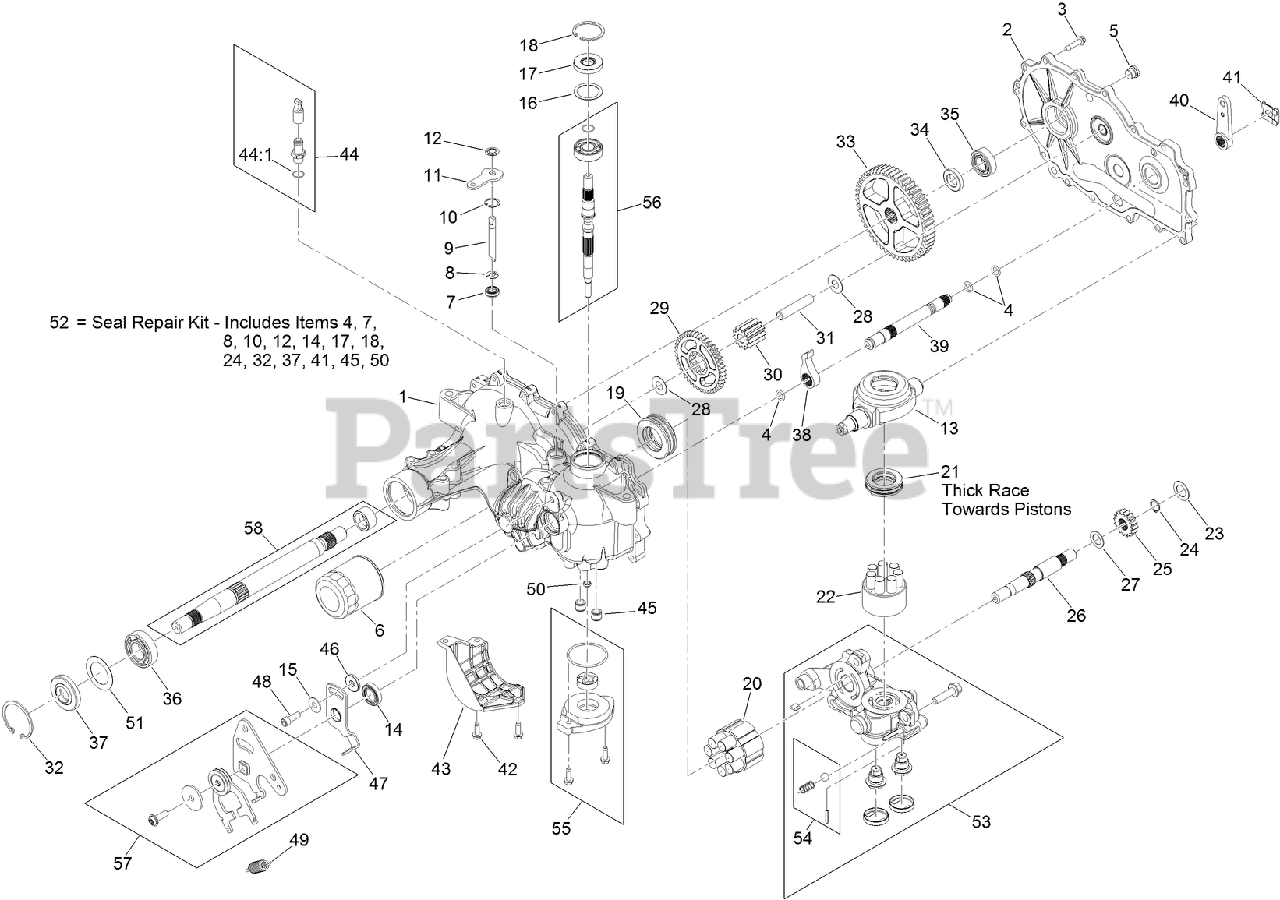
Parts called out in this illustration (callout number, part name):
1	MAIN HOUSING KIT
2	RH HOUSING SIDE KIT
3	SCREW-HHF
4	O-RING
5	PLUG-THREAD, STRAIGHT
6	ELEMENT-OIL FILTER, HYD
7	SEAL-LIP
8	RING-RETAINING, EXTERNAL
9	ROD-BYPASS
10	RING-RETAINING, INTERNAL
11	Arm-Bypass
12	RING-RETAINING, EXTERNAL
13	SWASHPLATE-TRUNNION
14	SEAL-LIP
15	WASHER
16	SPACER
17	SEAL-LIP
18	RING-RETAINING
19	Bearing-Thrust
20	MOTOR CYLINDER BLOCK KIT
21	BEARING-THRUST
22	PUMP BLOCK ASM
23	WASHER-FLAT
24	RING-RETAINING
25	GEAR-16T
26	SHAFT-MOTOR
27	WASHER
28	WASHER
29	GEAR-43T
30	GEAR-11T
31	PIN-JACKSHAFT
32	RING-RETAINING
33	GEAR-54T
34	SPACER
35	BEARING-BALL
36	BEARING-BALL
38	PAWL-BRAKE
39	SHAFT-BRAKE, INBOARD
40	HANDLE-BRAKE
41	RING-RETAINING, EXT
43	GUARD-FILTER, RH
44	ADAPTER-STRAIGHT
44:1	O-RING
45	TUBE-CHARGE
46	SPACER
47	ARM-NEUTRAL, RIGHT
48	Screw-Sh
49	SPRING-EXTENSION
50	SEAL-GEROTOR
51	SPACER
52	SEAL KIT
53	RH CENTER SECTION CHARGE KIT
54	CHARGE RELIEF KIT
55	CHARGE KIT
56	INPUT SHAFT KIT
57	CONTROL ARM KIT
58	AXLE SHAFT KIT
